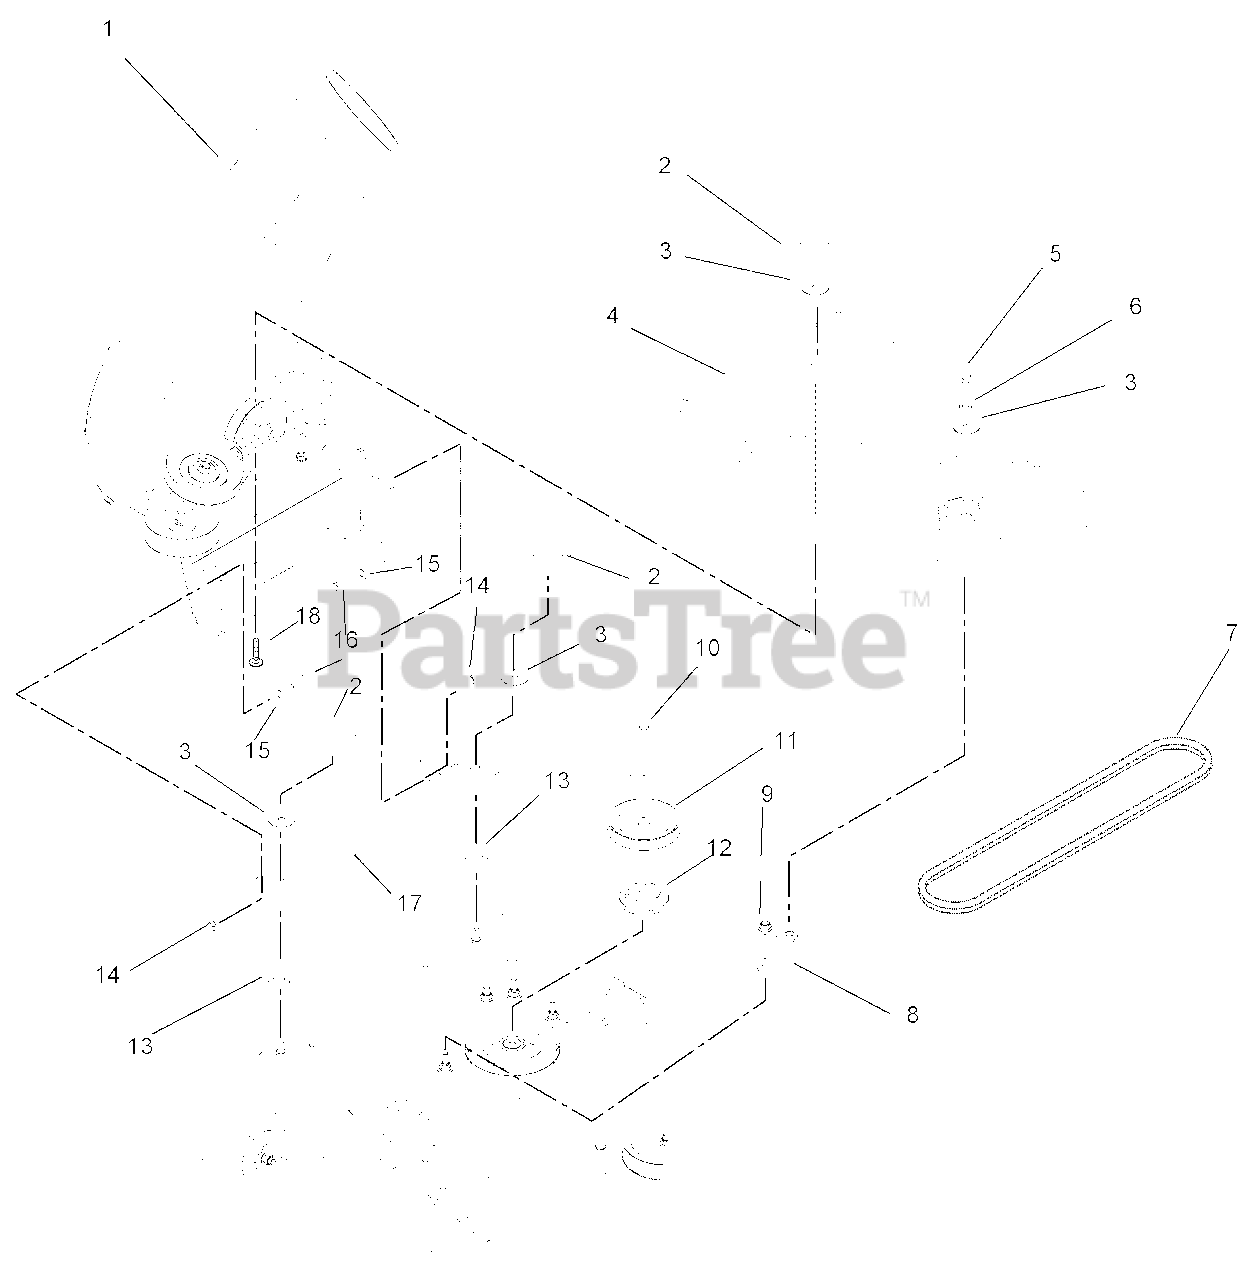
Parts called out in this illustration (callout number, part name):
1	BLOWER (SERVICE ASSEMBLY)
2	KNOB - WING .312-18 UNC
3	WSHR-FL-STL .380X1.50X.062 YWZ
4	BELT COVER W/DECAL
5	@BLT-HEX .38-16X1.00 GR5 YWZC
6	@WSHR-LK .38X.094 REG YWZC
7	V-BELT, 4L-RAW EDGE
7	V-BELT, HA-WRAPPED
8	WMT, XL BLOWER COVER STANDOFF
9	@NUT-LK-NYL-FLG .31-18 YWZC
10	BLT-HEX .38-16X1.75 GR8 M-EPYZ
11	SHEAVE, 4.00 DIA.
12	ASSEMBLY, SHEAVE ADAPTER
13	WSHR-FL-STL .656X1.250X.10 YZC
14	@NUT-LK-NYL-FLG .25-20 YWZC
15	@WSHR-FL-STL.281X.62X.065 YWZC
16	@BLT-HEX .25-20X1.00 GR5 YWZC
17	WMT, BLOWER BRACKET
18	@BLT-RDHDSQNK .31-18X1.50 G5YZ
